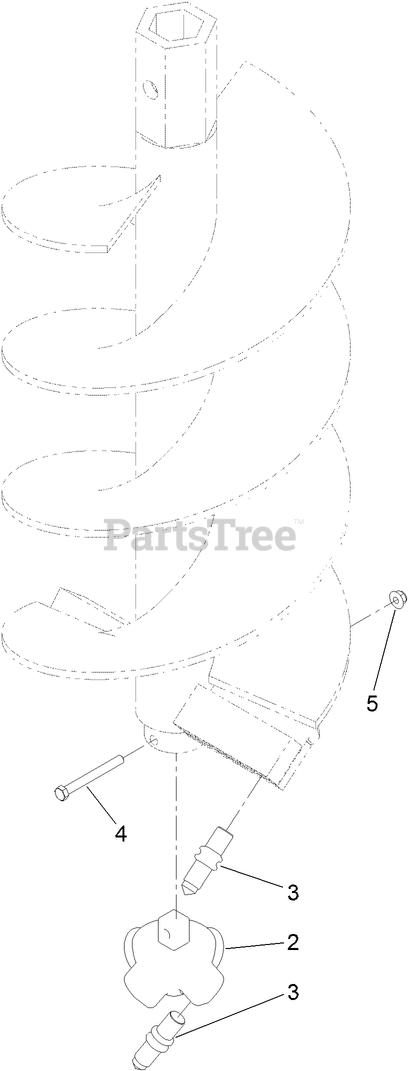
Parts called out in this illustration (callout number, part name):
2	PILOT-AUGER, ROCK
3	TOOTH-BULLET
4	SCREW-HH
5	NUT-HF, NI
